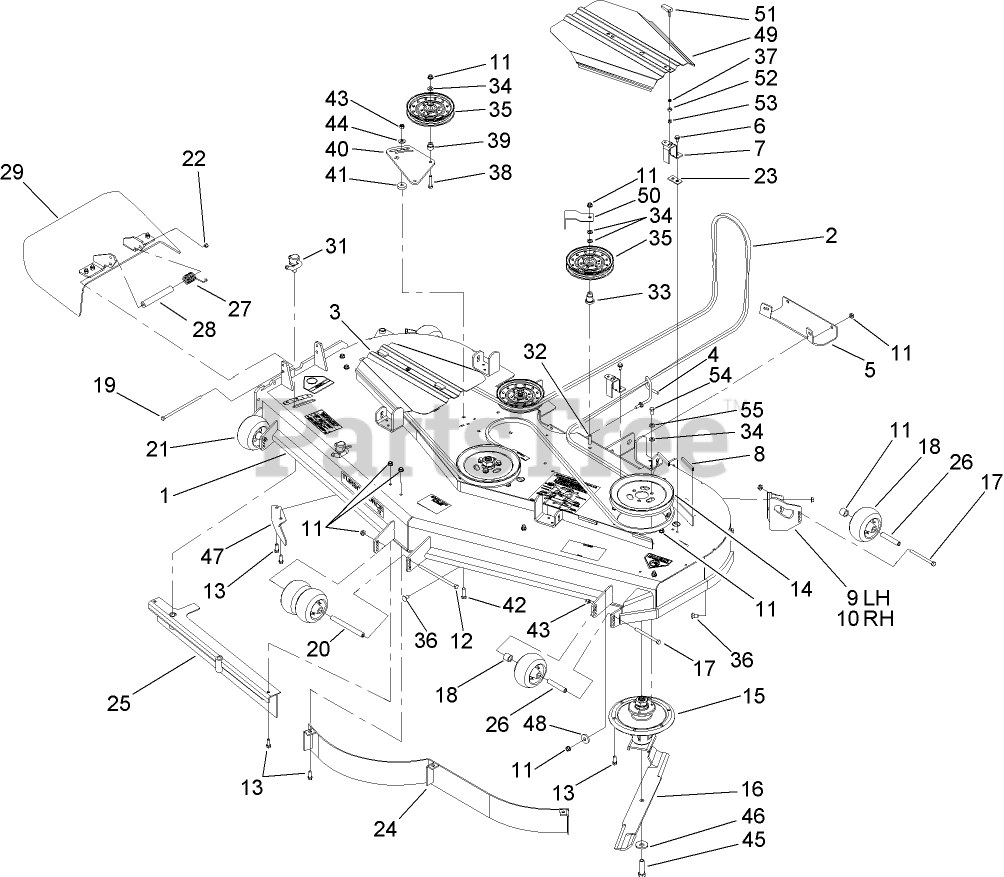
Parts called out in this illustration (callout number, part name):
1	Deck Decal ASM
3	COVER-BELT, RH
4	GUIDE-BELT
5	Plate-Skid
6	SCREW-HWHTF
7	BRACKET-COVER
8	STRIP-SEAL
9	MOUNT-WHEEL, LH
10	MOUNT-WHEEL, RH
11	NUT-HHF, WHIZ
12	SCREW-HH
13	SCREW-HWH
14	Pulley
15	SPINDLE ASM
16	BLADE-HI FLOW, 24.5 INCH
17	SCREW-HH
18	TUBE-SPACER
19	SCREW-HH
20	SPACER-WHEEL
21	ROLLER-SCALP, ANTI
22	NUT-LOCK, NI
23	SPACER-COVER, BELT
26	TUBE-SPANNER
27	SPRING-TORSION
28	SPACER
29	RUBBER DEFLECTOR ASM
31	LEVER ASM
32	SCREW-HH
33	MOUNT-PULLEY
34	WASHER-FLAT
35	Idler-Flat
36	SCREW-CARR
37	WASHER
38	SCREW-HH
39	BUSHING-IDLER
40	Plate-Idler
41	Spacer
42	SCREW-CARR
43	NUT-LOCK, NI
44	WASHER-BELLEVILLE
45	SCREW-BLADE
46	Washer-Blade Bolt, Heavy
47	BAFFLE-DISCHARGE
48	WASHER
49	COVER-BELT, LH
50	GUIDE-BELT
51	HANDLE-LATCH, SWELL
52	BUSHING-LATCH, SWELL
53	NUT-LOCK, HH
54	SCREW-HH
55	WASHER-BELLEVILLE
